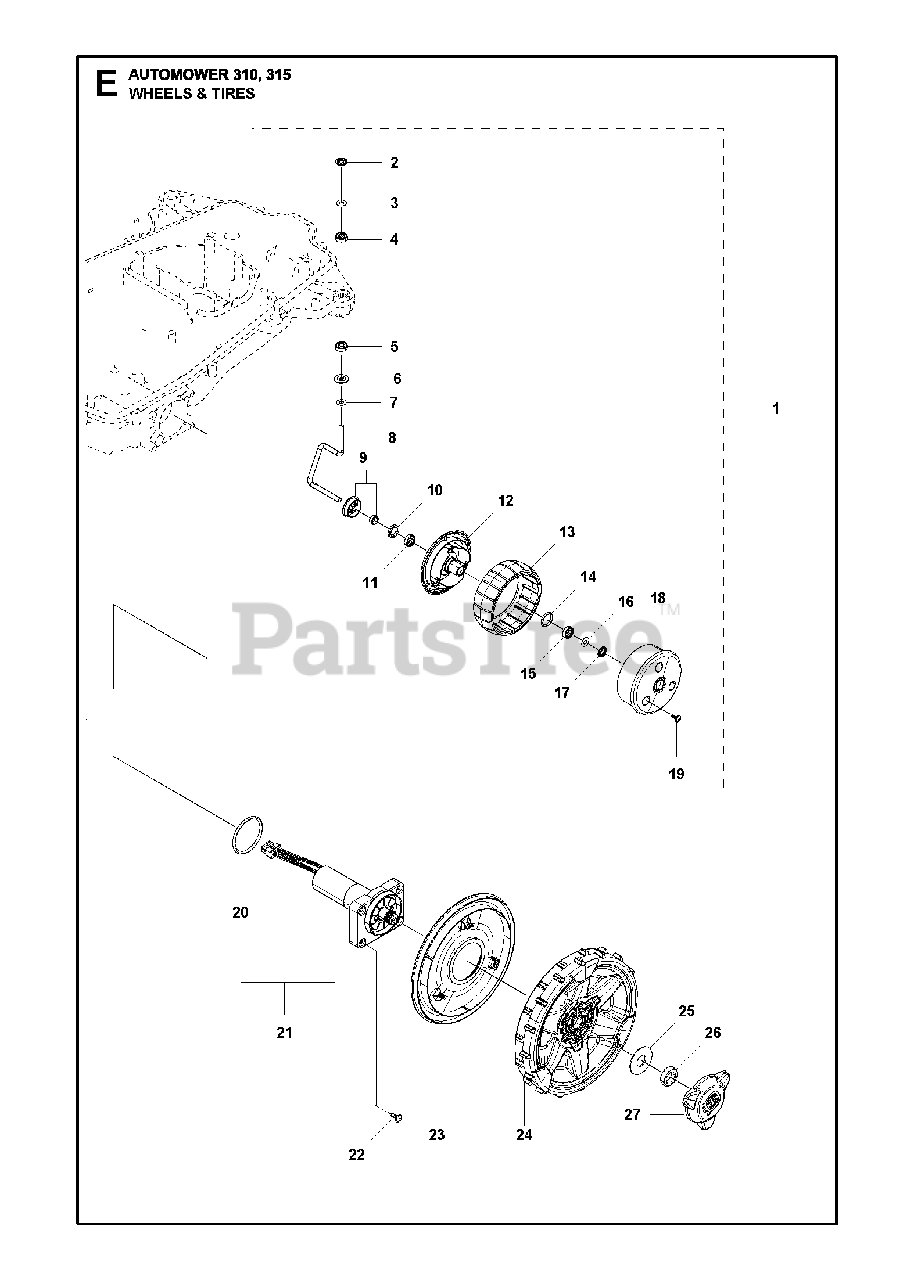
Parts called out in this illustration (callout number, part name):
1	WHEEL KIT FRONT
2	LOCKWASHER STARLOCK SS 6MM GEO
3	WASHER FRONT WHEEL 6MM
4	BALL BEARING SINGLE ROW S696
5	BALL BEARING SINGLE ROW S696
6	WASHER
7	WASHER FRONT WHEEL 6MM
8	SPINDLE FRONT WHEEL 6 MM
9	SHIELD KIT
10	SEALING 12X18X3
11	BALL BEARING SINGLE ROW S696
12	WHEEL FRONT WHEEL INSIDE
13	WHEEL RUBBER TYRE
14	O-RING 2,62X15,54
15	BALL BEARING SINGLE ROW S696
16	WASHER FRONT WHEEL 6MM
17	LOCKWASHER STARLOCK SS 6MM THI
18	WHEEL FRONT WHEEL OUTSIDE
19	SCREW 14MM
20	O-RING LIGHT GREY
21	MOTOR KIT
22	SCREW ITXPANT
23	COVER REAR WHEEL
24	REAR WHEEL FINE THREAD
25	WASHER WASHER REAR WHEEL 16X40
26	HEXAGON THIN NUT
27	HUB CAP REAR WHEEL NO CENTER P
